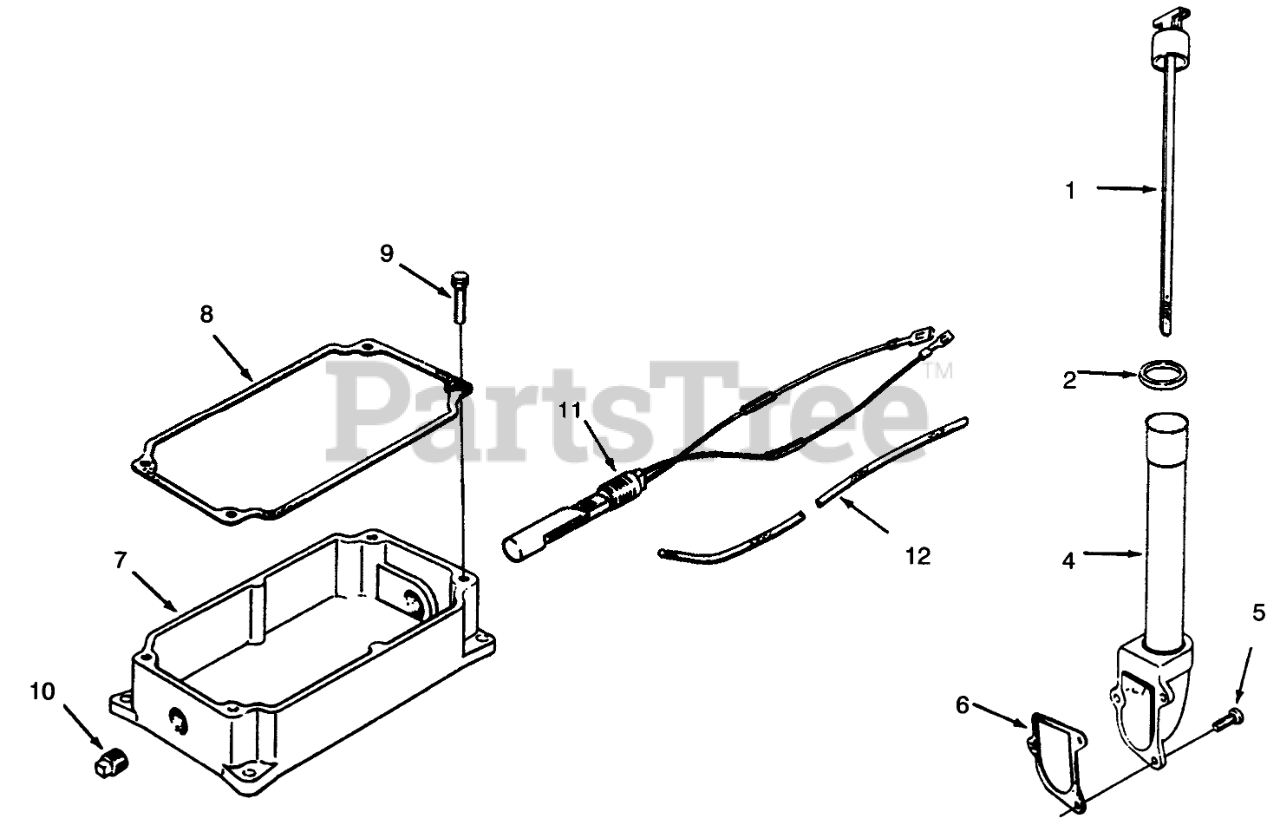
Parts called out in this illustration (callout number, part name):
1	Dipstick
2	0-Ring
4	Adapter-Oil Fill
5	Screw
6	Gasket
7	Oil Pan
8	Gasket
9	Screw
11	Kit-Float Switch (Includes Items 12 & Decal)
12	Sleeve
